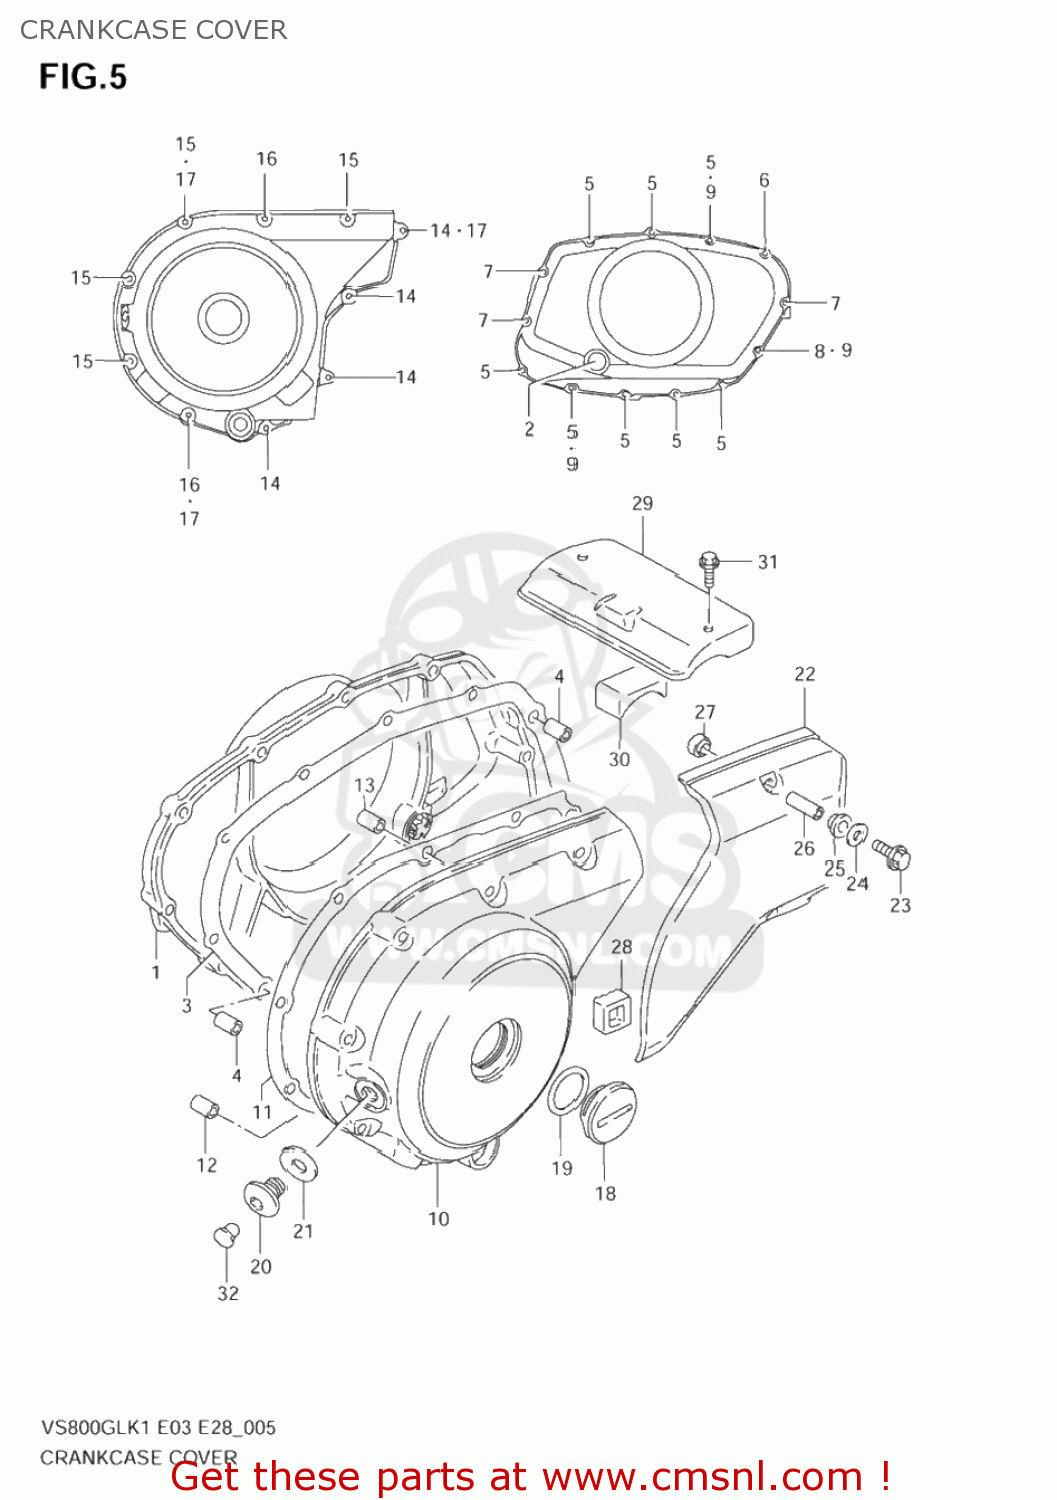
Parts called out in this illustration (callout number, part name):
1	COVER,CLUTCH
2	LENS,OIL LEVEL CHECK
3	GASKET,CLUTCH COVER (NAS)
4	PIN
5	BOLT
6	BOLT
7	BOLT
8	BOLT
9	GASKET(5.8X13X1.2) (NAS)
10	COVER,GENERATOR
11	GASKET,GENERATOR COVER (NAS)
12	PIN(8.4X11X20)
13	PIN
14	BOLT
15	BOLT
16	BOLT
17	GASKET(5.8X13X1.2) (NAS)
18	Chrome Crankshaft Plug
19	O RING(D:3.1,ID:32.7)
20	PLUG,14X12
21	GASKET(13.8X18.8X4.8) (NAS)
22	COVER,SECONDARY GEAR CASE
23	BOLT
24	WASHER(6.5X14X1.6)
25	WASHER(8.7X15X2.1)
26	SPACER(6.5X9X33.3)
27	WASHER(8.7X16X5)
28	DAMPER,SECONDARY COVER
29	COVER,STARTER MOTOR
30	DAMPER,MOTOR COVER
31	BOLT
32	CAP(OD:12)
